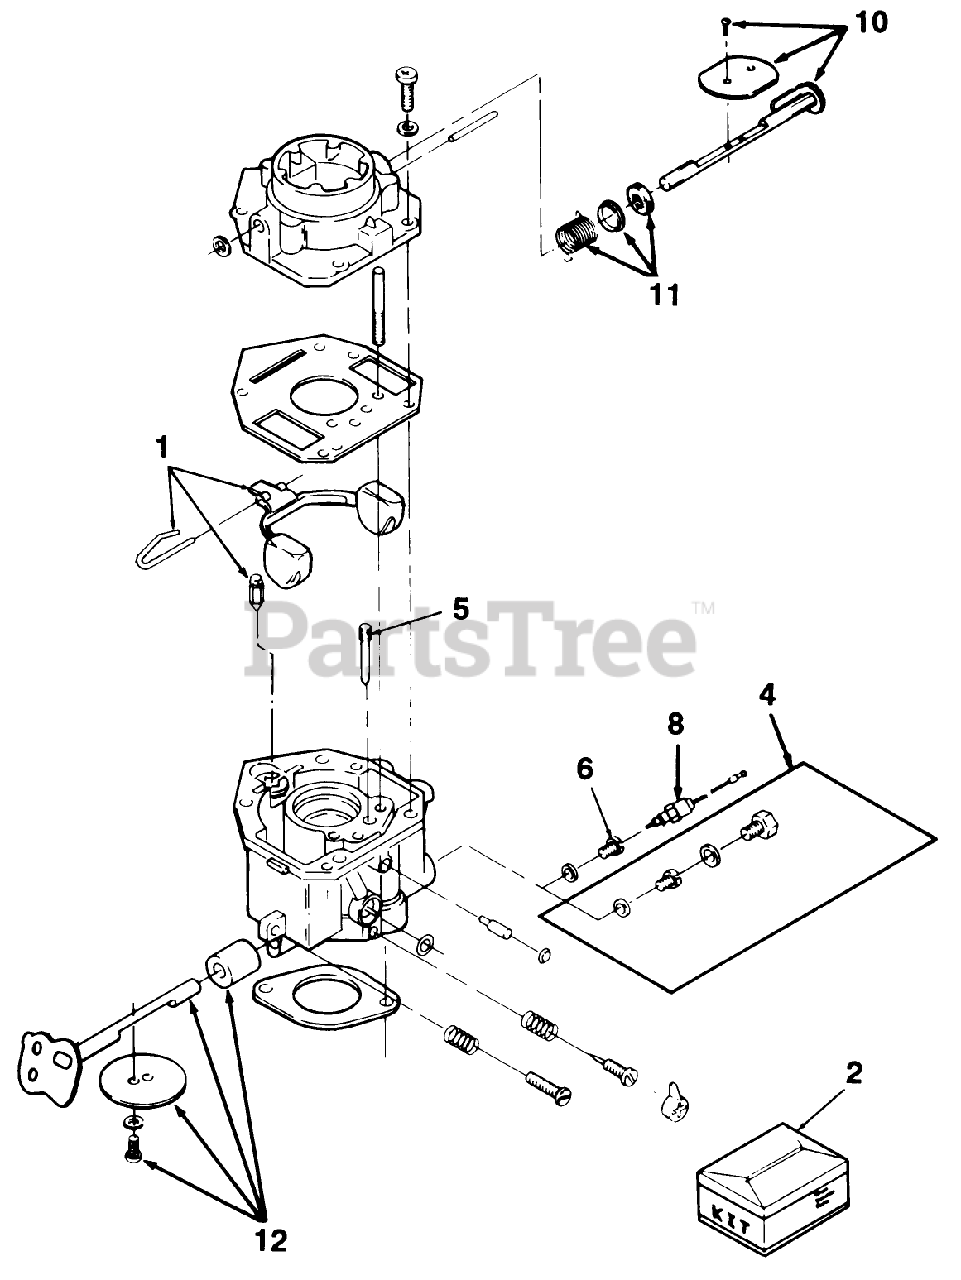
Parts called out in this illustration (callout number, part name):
1	Float Kit (Includes Float, Pin and Valve)
2	Repair Kit (Includes Screw and Plug Package, Gasket Package, Float Valve, Idle Adjustment Needle and Spring, Mounting Gaskets, Idle Limit Cap)
4	JET-FIXED, HIGH ALTITUDE
5	JET-IDLE
6	JET-POWER
8	Solenoid-Fuel Cut-Off (Includes Gasket)
10	Choke Shaft-Kit (Includes Choke Valve, Valve Set Screw & Air Filter)
11	Choke Lever-Kit (Includes Choke Lever Ring, Choke Spring & Choke Collar)
12	Throttle Shaft-Kit (Includes Valve Set Screw, Air Filter & Throttle Valve)
